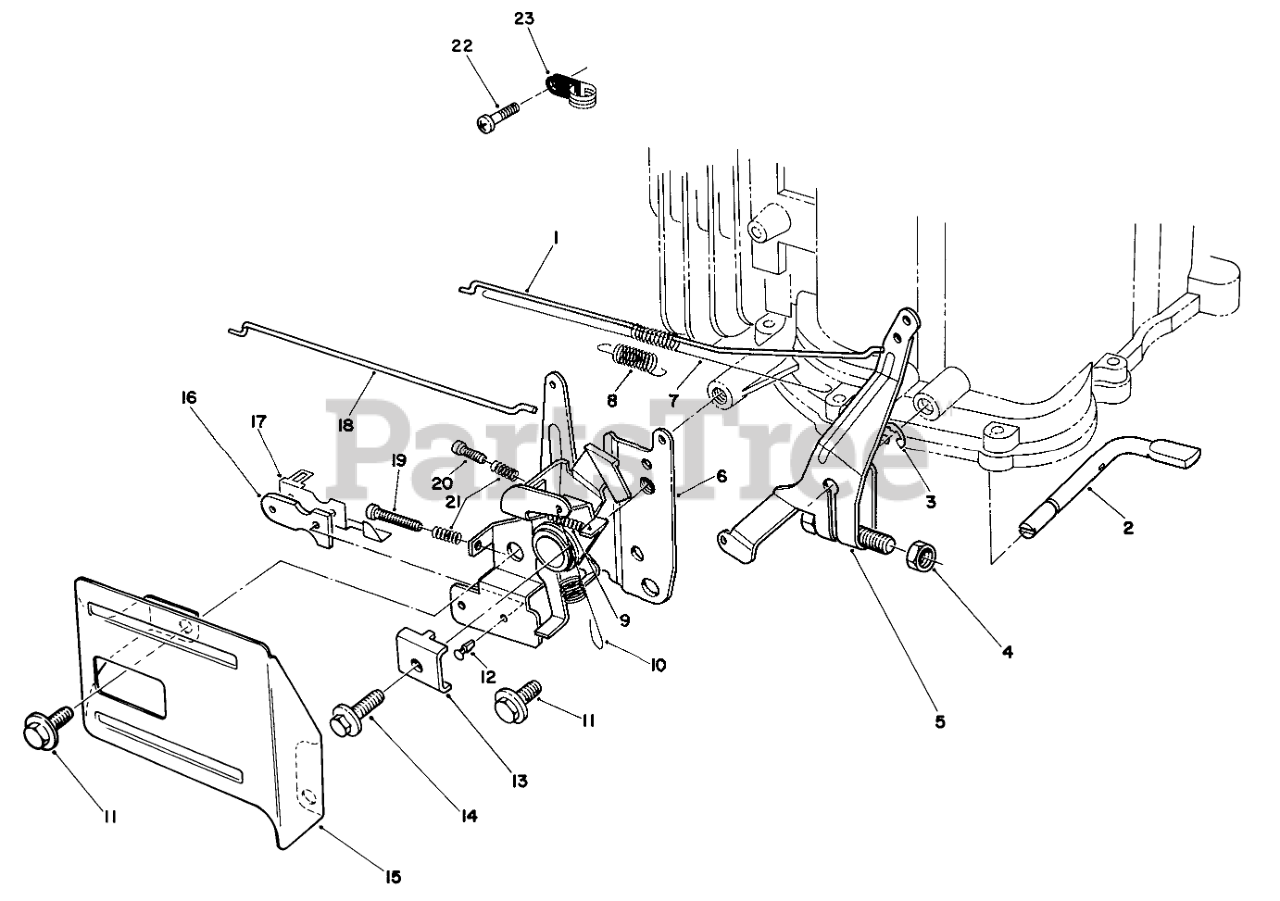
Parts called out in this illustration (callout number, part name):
1	Rod-Carburetor
2	SHAFT
3	E-RING
4	Nut
5	ARM ASM
6	THROTTLE
7	SPRING
8	SPRING
9	SPRING
10	SPRING
12	RIVET
13	CLAMP-CABLE
15	THROTTLE GUARD
16	INSULATOR-KILL SWITCH
17	TERMINAL-KILL SWITCH
18	Rod-Choke
19	SCREW
20	SCREW
21	SPRING
22	SCREW
23	Clamp
